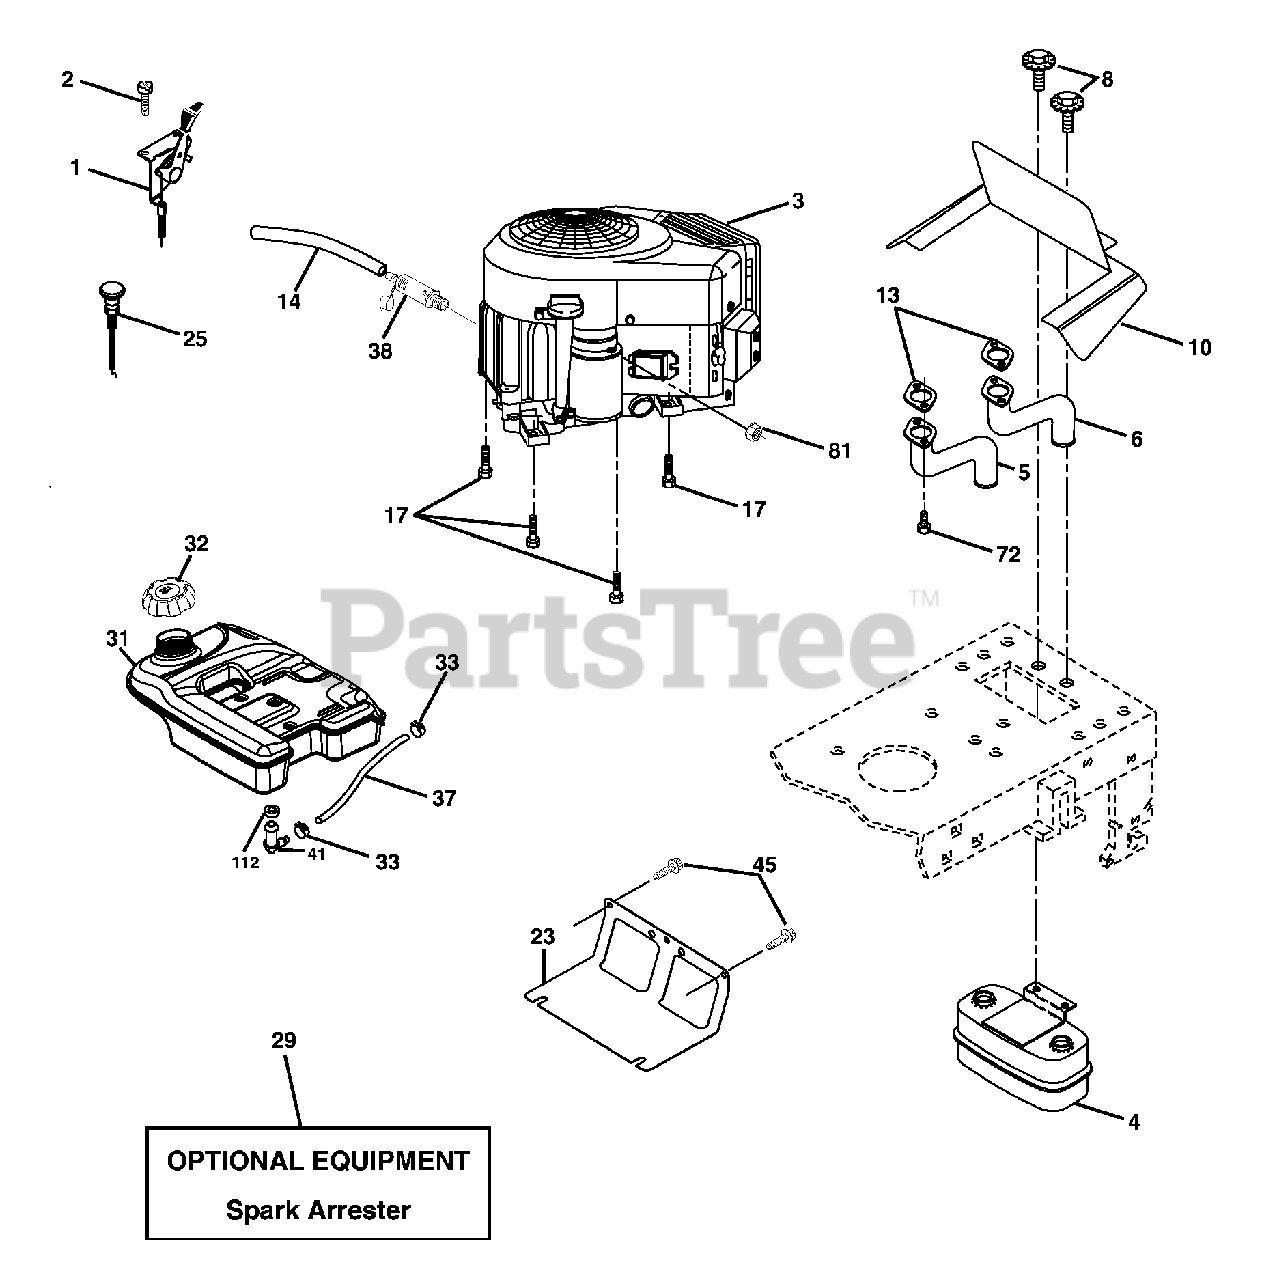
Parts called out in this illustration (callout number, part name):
1	Control Throttle
2	Screw 10 x 3/4 Single Lead-Hex
4	Muffler Asm Twin Lo-Tone
5	Pipe Exhaust LH
6	Pipe Exhaust RH
8	Bolt 5/16-18 unc x 3/4 w/Sems
10	Shield
13	Muffler Gasket
14	Tube Drain Oil Easy
17	Screw Thdrol 3/8-16 x 1-1/2
23	Shield Heat
25	Choke Control
29	Kit Spark Arrestor (Flat Scrn)
31	Tank Fuel 4.0 Rear
32	Cap Asm Fuel
33	Clamp Hose Black
37	Line Fuel
38	Plug Drain Oil
41	Stem Tank Fuel
45	Screw Hexwsh Thdr 3/8-16 x 3/4
72	Screw 5/16-18 x 1
81	Nut Keps Hex 1/4-20 unc
112	Bushing
